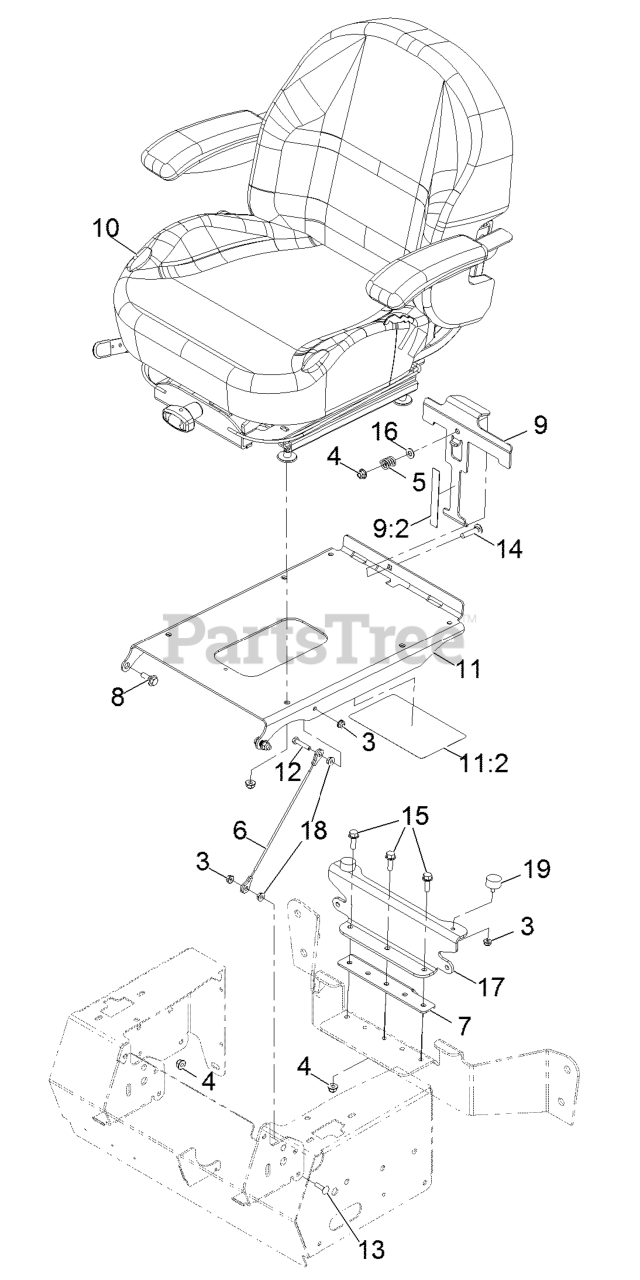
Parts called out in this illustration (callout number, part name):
4	NUT-HF, NI
5	SPRING-COMPRESSION
6	CABLE-STOP, SEAT
7	CATCH,SEAT LATCH
8	SCREW-SHOULDER
9	ASM-SEAT LATCH
9:2	STRIP-POLY WEAR
10	KIT-SEAT SUSPENSION
11	PLATE, SEAT W/DECALS
11:2	DECAL-SERVICE AID
12	SCREW-HH
13	SCREW-CARR
14	BOLT-CARR
15	SCREW-HHF
16	WASHER-PLAIN
17	PLATE-SEAT SUPPORT
19	BUMPER-RUBBER
